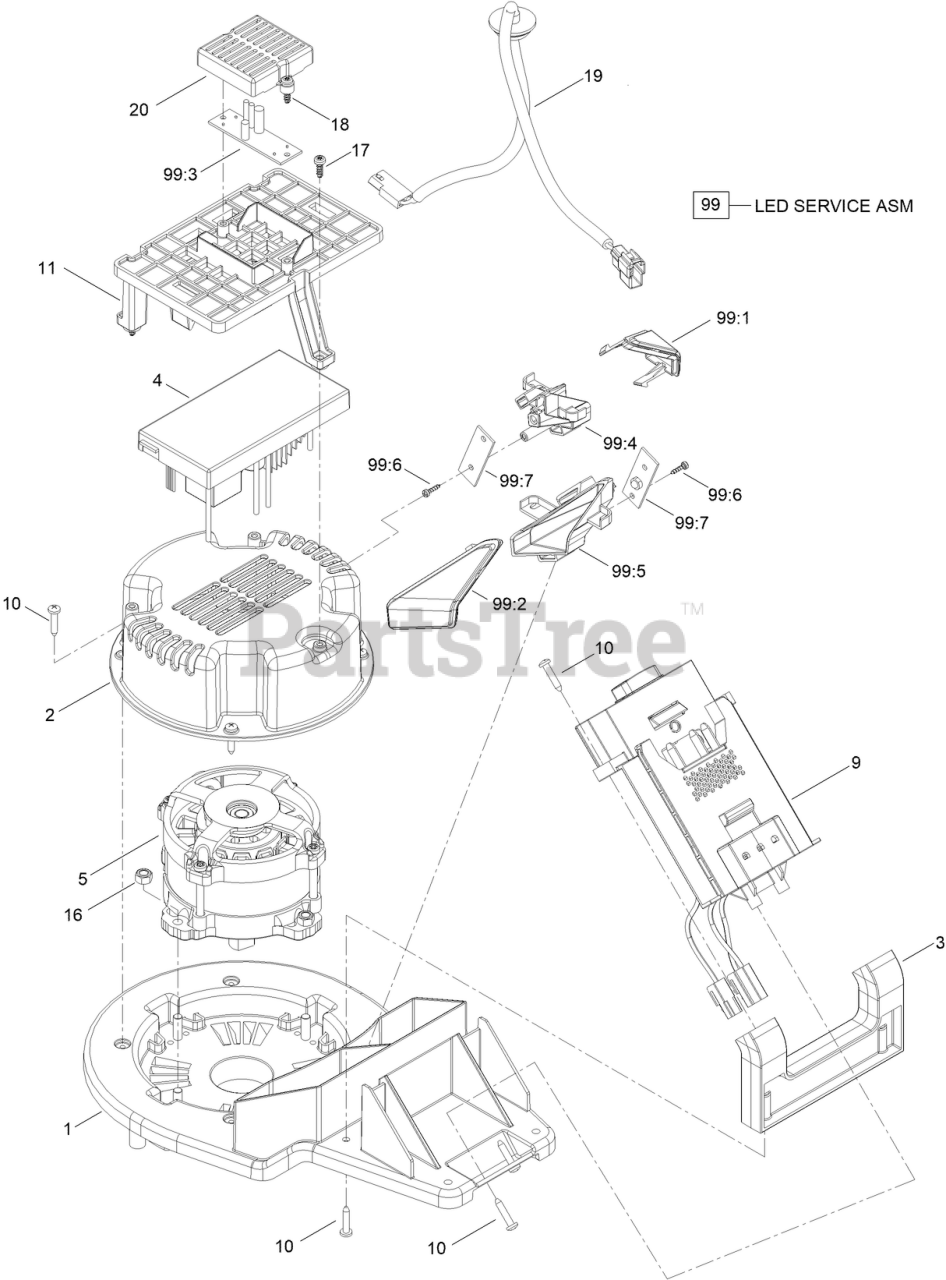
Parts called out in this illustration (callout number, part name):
1	ASM-MOUNT, MOTOR
2	COVER-MOTOR
3	SUPPORT-RECEIVER
4	CONTROLLER-MOTOR, EPP LED
5	MOTOR-1KW, 60V
9	BATTERY TRACK ASM
10	SCREW-PPH, ST4.2x20
11	BRKT-CONTROLLER
16	NUT-HEX, M6
17	SCREW-TPH, ST4.2x12
18	SCREW-TPH, ST4.2X16
19	ASM-WIRE, COBRA SP
20	COVER-DRIVER, LED
99	LED Service ASM
99:1	LENS-LED, RIGHT
99:2	LENS-LED, LEFT
99:3	BOARD-LED, CONTROL
99:4	HOUSING-LED, RIGHT
99:5	HOUSING-LED, LEFT
99:6	SCREW-PPH, ST3x12
99:7	LED-BOARD
